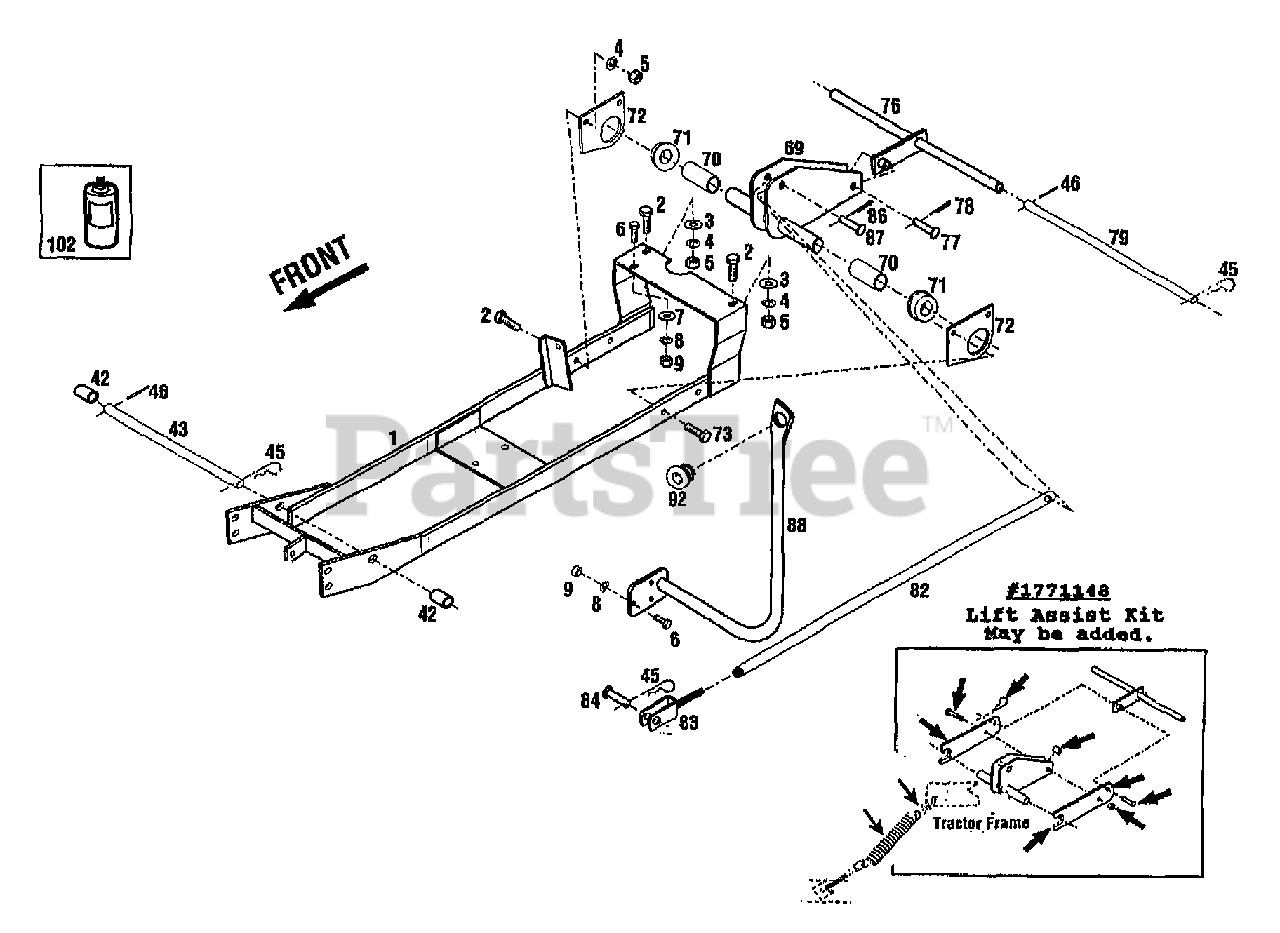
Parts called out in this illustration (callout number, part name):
1	ASSM-SUBFRAME (14078)
2	SCR-HH 3/8-16X1.0 G5 ZP
3	WASHER-FLAT 3/8 SAE
4	WASHER-LK .375 @ DEPL
5	NUT-HEX 3/8-16 ZP
6	SCR-HH 5/16-18X1.0 G5 ZP
7	WASHER-FLAT 5/16 SAE
8	WASHER-LK .312 ZP
9	NUT-HEX 5/16-18 ZP
42	SPACER (14078)
43	ROD-SUPPORT (14078)
45	PIN-HITCH .125X2.56 ZP
46	PIN-ROLL
69	ROD-LIFT WELDMENT (14078)
70	TUBE-TORQUE (14078)
71	BEARING-1" (14078)
72	PLATE-END (14078)
76	ASSM-LIFT (14078)
77	PIN-CLEVIS .5X2.0 ZP
78	PIN-COTTER .120X1.00 ZP
79	ROD-LIFT (14078)
82	SHAFT-LIFT (14078)
83	CLEVIS
84	PIN-CLEVIS
86	PIN-COTTER .120X1.00 ZP
87	PIN-CLEVIS
88	HANDLE-SUPPORT
92	GROMMET
102	PAINT-BLACK SPRAY
